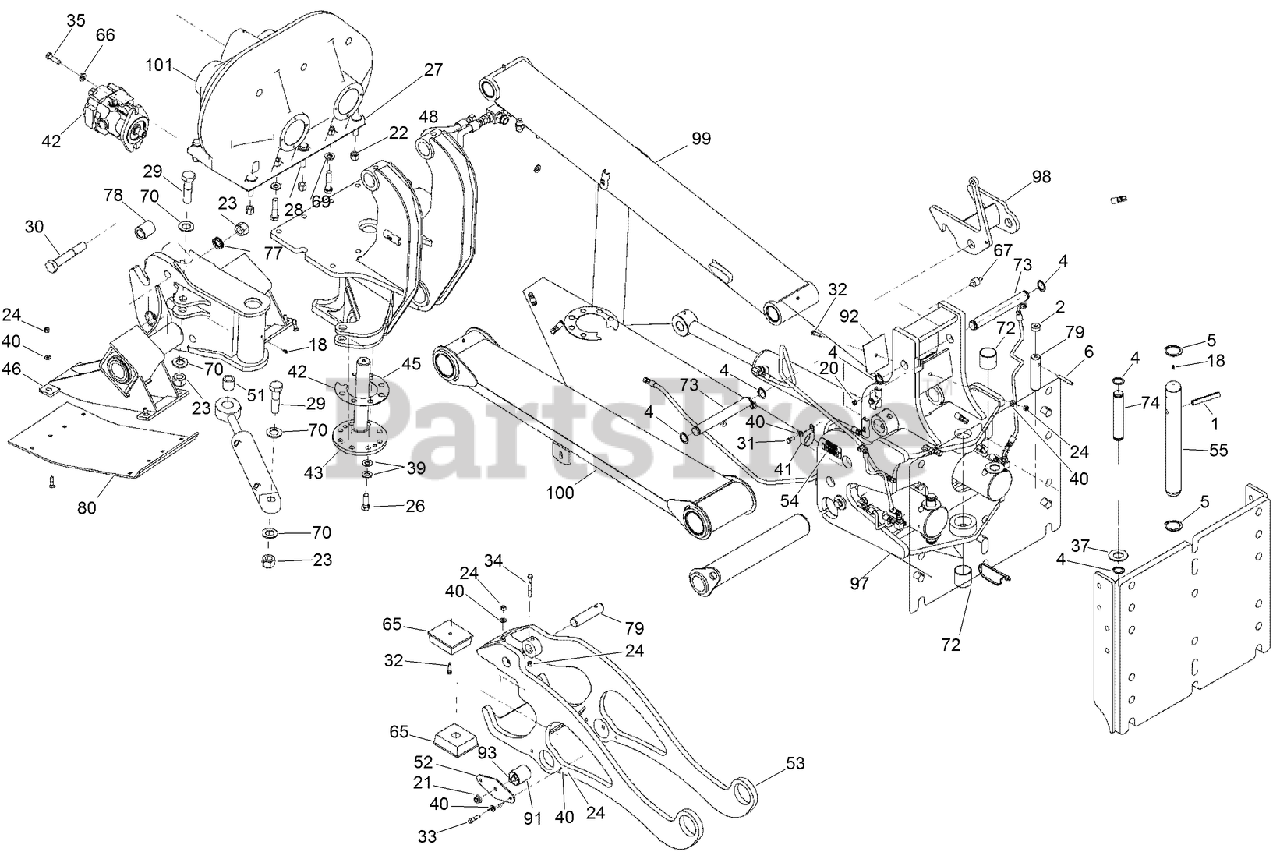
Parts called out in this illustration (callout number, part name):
1	PIN-SPIRAL
2	PLUG-FREEZE
4	RING-RETAINING
5	RING-RETAINING, EXTERNAL
6	PIN-ROLL
18	FITTING-Lube 1/4-28 Tpr SAE-LT .54 Long
20	NUT-Hex Serrated Flange, 5/16 inch NC
21	NUT-hex serrated flange, 1/2 inch NC
22	NUT-LOCK, HEX
24	NUT-HEX
26	SCREW-HH
27	BOLT-hex, 5/8 NC x 2-3/4 inch, grade 8
28	BOLT - Hex Hd 0.625 x 3.00 GR8 ZND
29	BOLT-HH
30	BOLT-HH
31	SCREW-HH
32	BOLT
33	BOLT-hex, 3/8 NC x 1-1/2 inch
34	BOLT-hex, 3/8 NC x 3 inch
35	BOLT-Hex Hd 1/2 x 1-3/4 GR5 ZND
37	WASHER-FLAT
39	WASHER - 0.656 x 1.312 x 0.095 in CST ZND
40	WASHER-FLAT
42	HYD MOTOR ASM
43	AXLE-PIVOT, BLADE MOUNTING
45	SHIM-PLOW PIVOT (THICK)
46	BRACKET-plow blade mounting
48	WELDMENT - Frame, Shaker
51	TUBE-ROD END SPACER
52	PLATE-bumper mounting
53	CRADLE-plow lift
54	PLATE - Serial Number
55	PIN - Plow Swing
65	BUMPER
67	MOUNT-RADIATOR
69	WASHER-FLAT
72	BEARING-PIVOT
73	PIN-PLOW
74	PIN - Plow Reel Carrier
77	WASHER-LOCK
78	TUBE-SPACER, SOD CUTTER
79	PIN-ROD
80	PLATE-skid shoe, 12 inch wide
91	MOUNT-ISOLATOR
92	SHIM-BUMPER
97	TOWER-plow swing
98	LATCH-transport, plow lift arm
99	ARM ASM-plow lift, upper
100	ARM ASM-plow lift, lower
101	Gearbox
